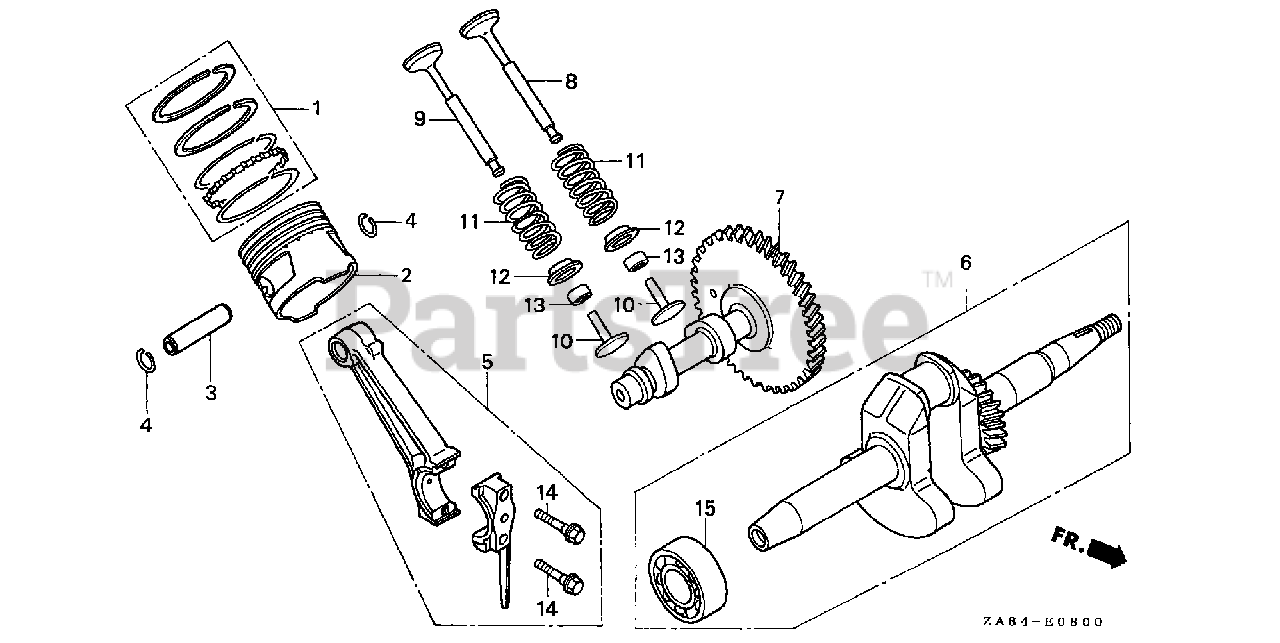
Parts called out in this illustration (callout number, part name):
1	RING SET, PISTON (STD)
1	RING SET, PISTON (OS 0.25)
1	RING SET, PISTON (OS 0.50)
1	RING SET, PISTON (0.75)
2	PISTON
2	PISTON (OS 0.25)
2	PISTON (OS 0.50)
2	PISTON (0.75)
3	PIN, PISTON
4	CLIP, PISTON PIN (10MM)
5	ROD ASSY., CONNECTING
5	ROD ASSY., CONNECTING (US)
6	CRANKSHAFT
8	VALVE, IN.
9	VALVE, EX.
10	LIFTER, VALVE
11	SPRING, VALVE
12	RETAINER, VALVE SPRING
13	ADJUSTER, TAPPET CLEARANCE
14	BOLT, CONNECTING ROD
15	BEARING, RADIAL BALL (6203)
